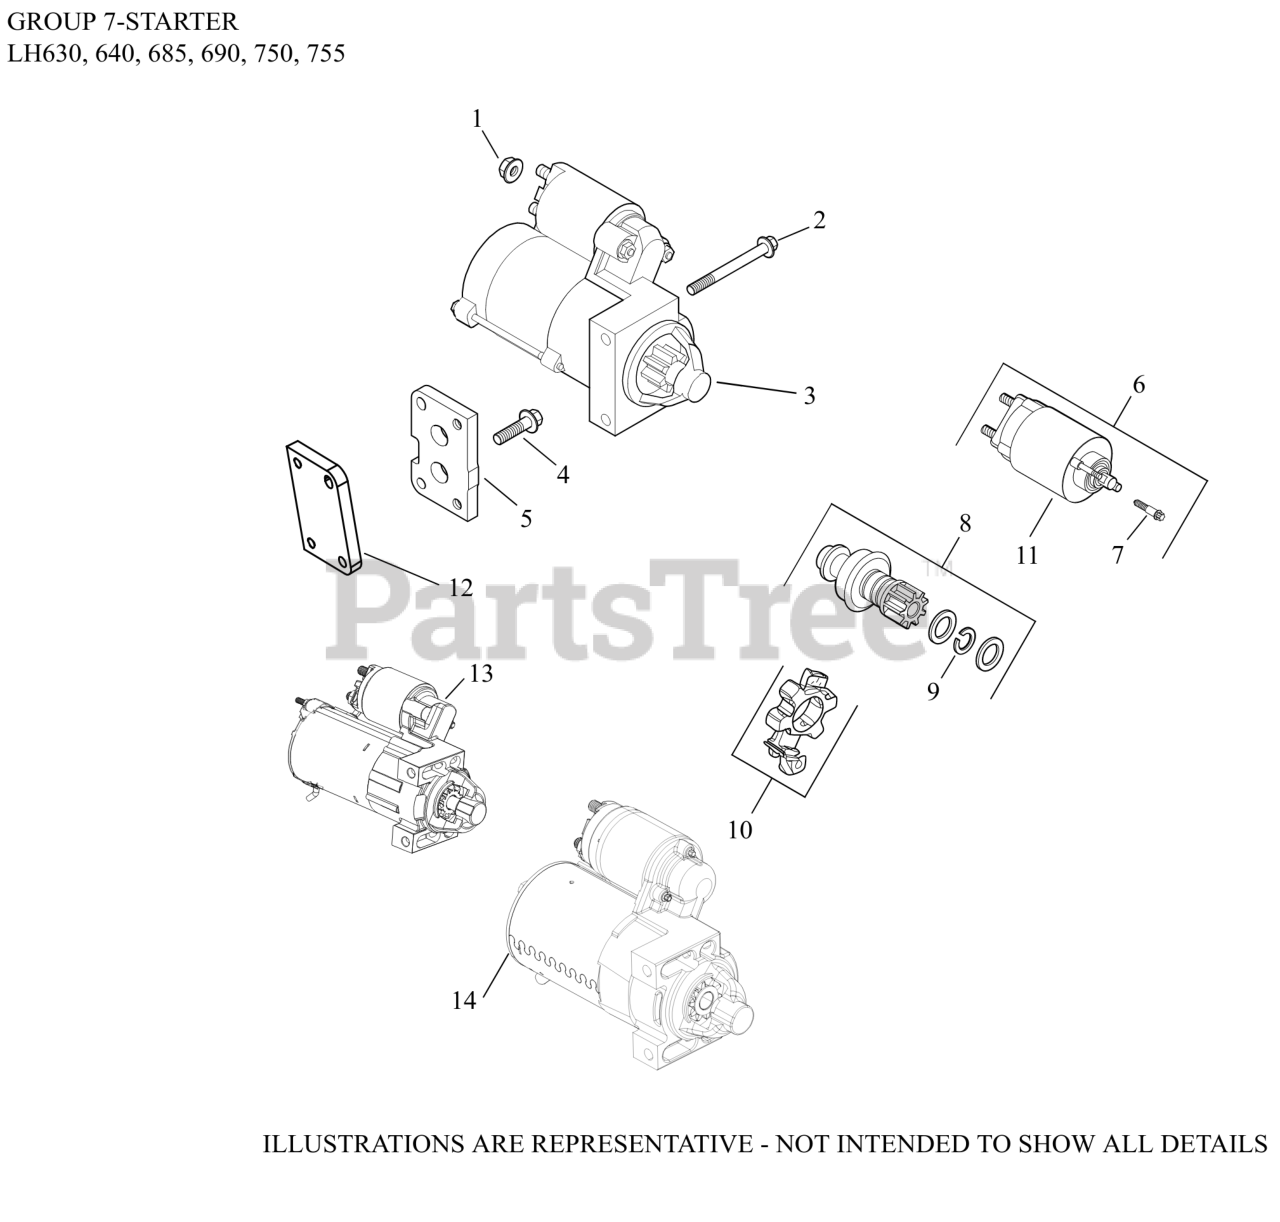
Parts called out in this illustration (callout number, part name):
1	NUT, FLG M8X1.25
2	SCREW, FLG M8X1.25X80
3	STARTER, SOLENOID SHIFT-(#2509824S)
4	SCREW, FLG M8X1.25X30
12	PLATE, STARTER
